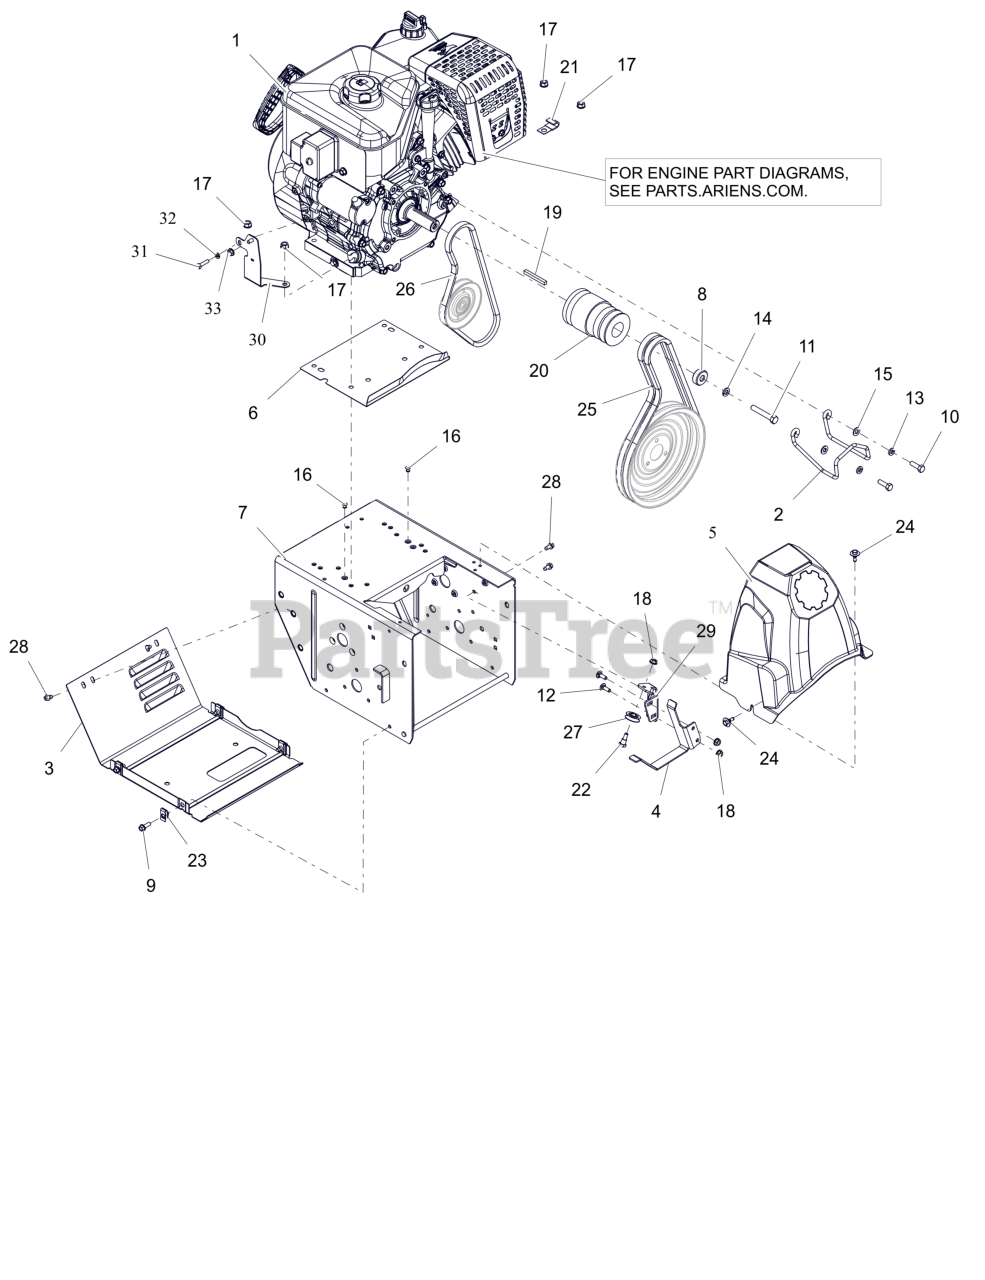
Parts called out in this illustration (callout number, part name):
1	ENGINE, AX420 GEN 3 120V/60W
2	FINGER, BELT
3	COVER, BOTTOM - VENTILATED
4	FINGER, BELT - FLAT
5	COVER, BELT
6	BAFFLE, WATER - LARGE BLOCK
7	FRAME, MAIN - PRO (WELDMENT)
8	BSHG, SPCR .406 X 1.250 X .500
9	BLT, HWH .25-20X.75 G5 ZCC
10	BLT, HEX 0.3125-24X1 G5 ZCC
11	BLT, HEX .38-24X2.25 G5 ZCC
12	BLT, RHSN .25-20X.750 G5 ZCC
13	WSHR, LK-HVY .312X.097 ZCC
14	WSHR,LK-REG .375X.094 ZCC
15	WSHR,FLT .344X.688X.065 ZCC
16	RVT, POP .1875 ZCC
17	NUT,LK-CTR-FLG .31-18 GF ZCC
18	NUT-LK-TOP-FLG .250-20 GF ZCC
19	KEY .25X.25X2.25
20	SHEAVE, COMBO HYDRO TRACK 4L
21	J-CLAMP
22	BOLT, SHLDR -.375 X .375 X .25-20
23	NUT-RTNR .25-20X.56
24	SCR-TAP .25-20X.5 CAPTIVE
25	V-BELT, HA-RAW EDGE (SET)
26	V-BELT, 4L-WRAPPED
27	PULLEY, CABLE
28	SCR-TAP .25-20X.50 HWH ZCC
29	BRACKET, CLUTCH CABLE
30	WLDMT- LG BLOCK FUSE MOUNT
31	BLT,HEX M6-1X25 G8.8 ZC120
32	WSHR,LK-REG .250X.062 ZCC
33	NUT-LK-CTR-FLG .25-20 ZC120
